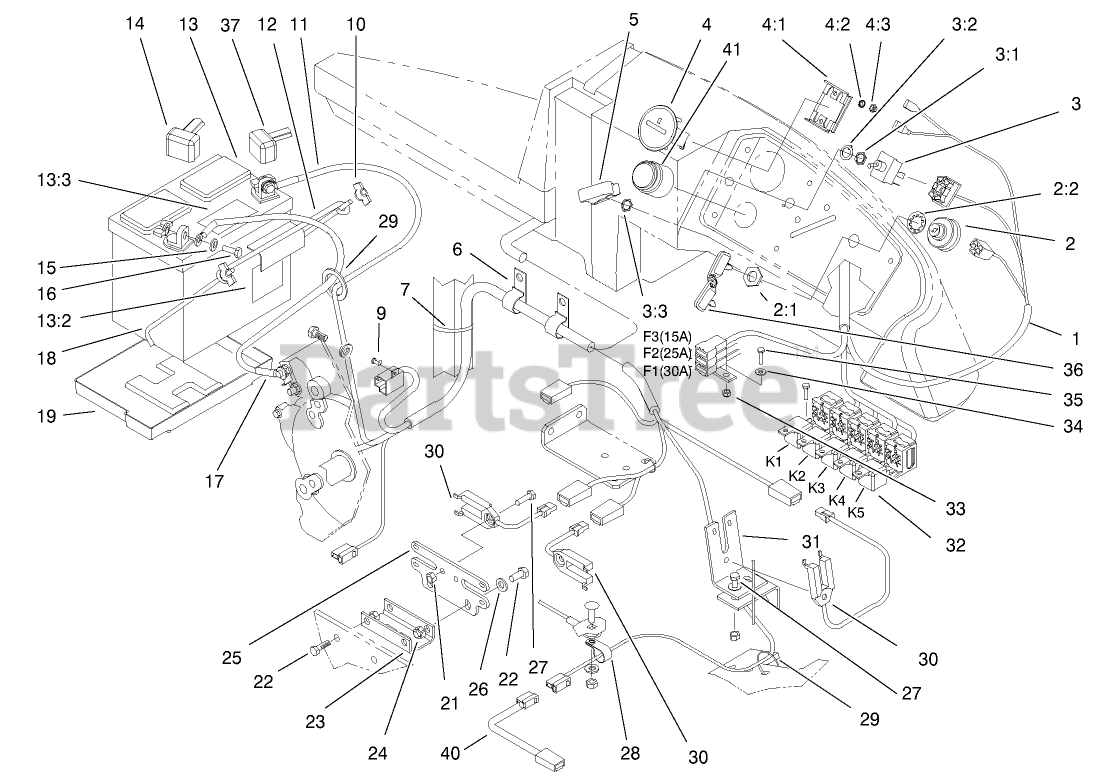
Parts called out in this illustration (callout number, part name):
1	HARNESS
2	IGNITION SWITCH ASM
2:2	WASHER-LOCK
3	SWITCH-TOGGLE, SEALED
3:1	NUT-HEX, SPECIAL
3:2	TAB-WASHER
4	Hourmeter
4:1	CLAMP-HOUR METER
4:2	WASHER-LOCK
4:3	NUT-HEX
5	COVER-PTO SWITCH
6	CLAMP-J
7	TIE-CABLE
9	SCREW-TAP
10	NUT-WING
11	WIRE ASM (NEGATIVE)
12	HOLDDOWN-BATTERY
13	ASM-BATTERY W/DECALS
13:2	DECAL-BATTERY
13:3	DECAL-DANGER
14	BOOT-TERMINAL
15	WASHER-FLAT
16	SCREW-HH
17	WIRE ASM
18	RETAINER-BATTERY
19	TRAY-BATTERY
21	NUT-LOCK, NI
22	SCREW-HH
23	CHANNEL-MOUNT, SWITCH
24	NUT-LOCK, NI
25	PLATE-MOUNT, SWITCH
26	WASHER-PLAIN
27	SCREW-HH
28	CLAMP-R
29	TIE-CABLE
30	SWITCH-INTERRUPTER
31	ANGLE - MOUNT,SWITCH
32	RELAY
33	NUT-LOCK, NI
34	WASHER-FLAT
35	SCREW-HWH
36	KEY-IGNITION
37	BOOT-TERMINAL
40	HARNESS - SEAT ADAPTER
41	AUDIO ALARM ASM
